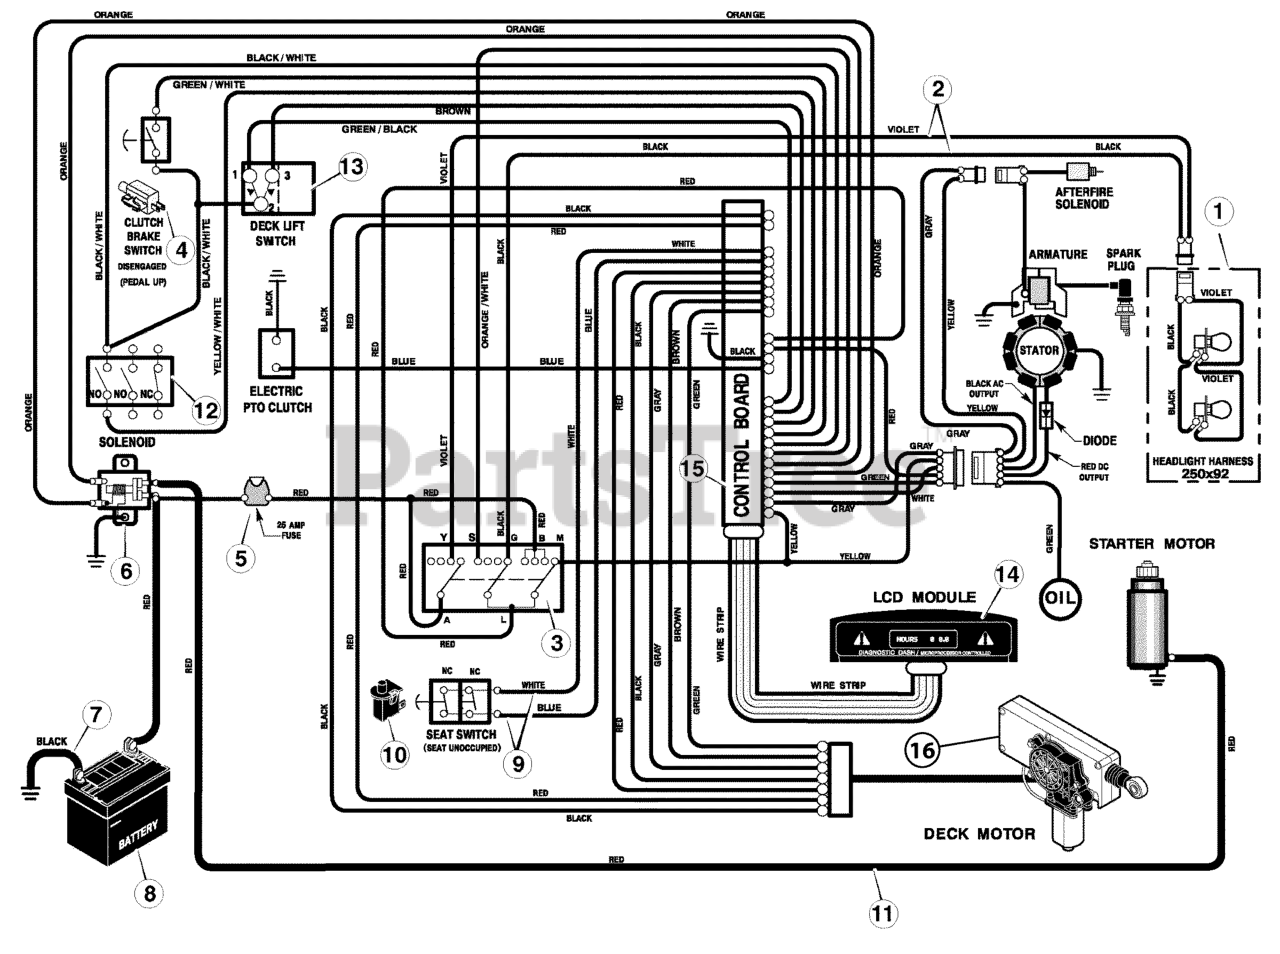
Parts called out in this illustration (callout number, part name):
1	Harness, Light Wire
1	Socket, Light
1	Bulb, Light
2	Harness, Chassis Wire
3	Switch, Ignition
3	Key, Ignition
3	Nut, Hex
3	Cap, Ignition
4	Switch, Limit
5	Fuse 25 AMP
5	Holder, Fuse
6	Solenoid
6	Screw, Mounting
6	Locknut
7	Cable, Battery Ground
7	Screw, Ground Cable
8	Battery
8	Bolt, Carriage
8	Wingnut
9	Harness, Seat Switch Wire
10	Switch, Seat Sensor
11	Cable
12	Switch, Electric PTO
13	Switch, Lifter
14	LCD Module
15	Contol Board Module
15	Key, English Electrical
15	Key, French Electrical
16	Lift Assembly, Deck
